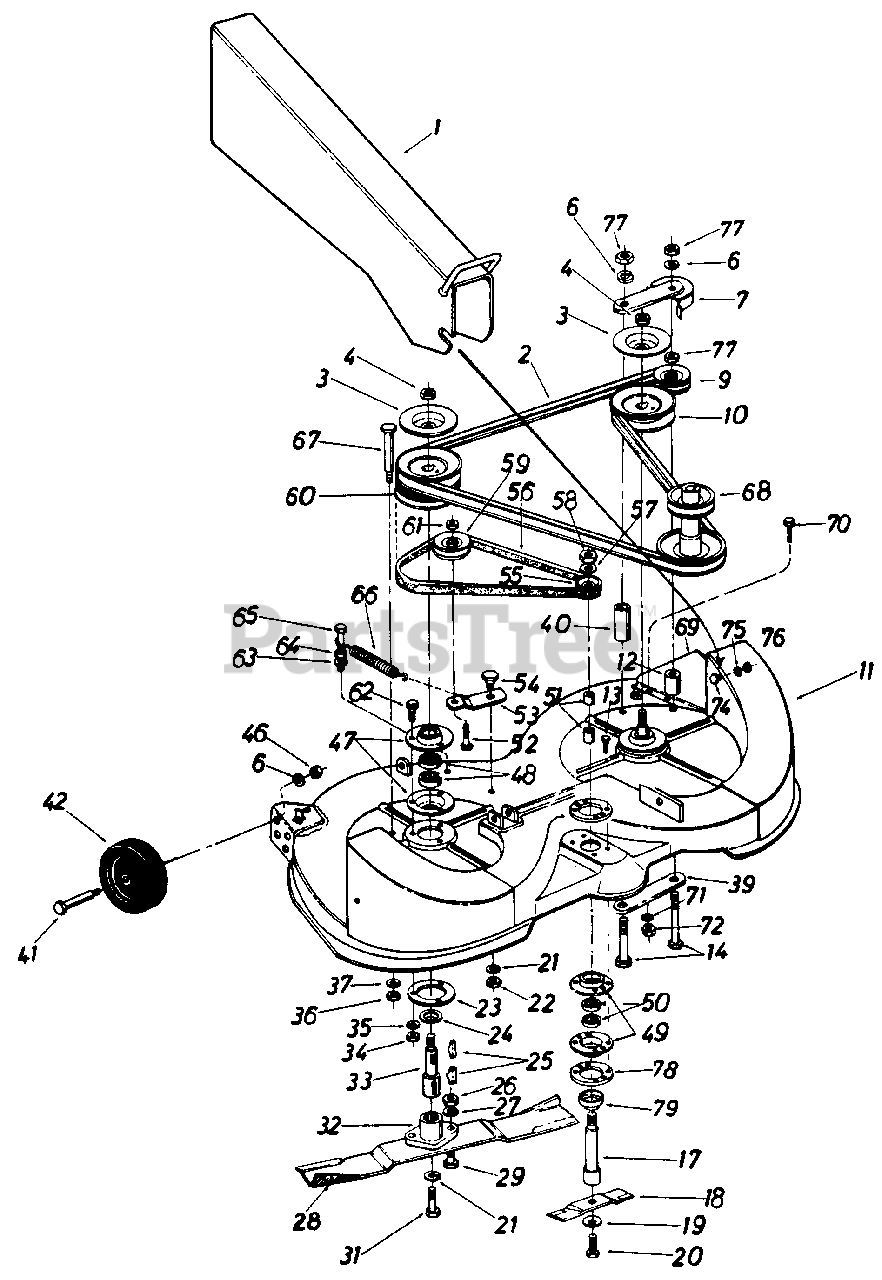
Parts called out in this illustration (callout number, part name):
1	Chute Extension Ass'y. L.H.
2	"V"-Belt
3	Brake Disc
4	Hex Cent. L-Nut 5/8-11 Thd.
6	L-Wash. 3/8" I.D.
7	Idler Pulley Belt Guard Ass'y.
9	5/8-V Belt Idler 8.50" O.D.
10	5/8-V Pulley .628N I.D. x 5.25" O.D.
11	40" Rear Discharge Deck
12	Spacer .40" I.D. x 1.25" O.D. x 1.59" Lg.
13	Hex B-Tap Scr. 1/4" x 1.0"
14	Hex Bolt 3/8-24 x 3.75" Lg.
17	Blade Spindle
18	6.50" Blade
19	Bell-Wash. 40" I.D. x .88" O.D.
20	Hex Bolt 3/8-24 x .87" Lg.
21	L-Wash. 3/8" I.D.
22	Hex L-Nut 3/8-16 Thd.
23	Plate Deck Reinforcement
24	Bearing Shield
25	#6 Hi-Pro Key 5/32 x 5/8" Dia.
26	Hex Nut 5/16-24 Thd.
27	L-Wash. 5/16" I.D.
28	20" High Lift Blade R.H.
29	Hex Bolt 5/16-24 x l.OO" Lg. (Grade 5)
31	Hex Bolt 3/8-24 x 1.50" Lg. (Grade 5)
32	Blade Adapter Kit
33	Blade Spindle
34	Hex Nut 5/16-18 Thd.
35	L-Wash. 5/16" I.D.
36	Hex L-Nut 3/8-16 Thd.
37	L-Wash. 3/8" I.D.
39	Reinforcement Plate
40	Spacer 3/8" I.D. x 50" O.D. x 2.72"
41	Shld. Bolt .498" Dia. x 1.53" Lg.
42	Cutting Deck Wheel
46	Hex Jam Nut 3/8-16 Thd.
47	Bearing Housing
48	Ball Bearing .787" I.D. x 1.85" O.D.
49	Bearing Housing
50	Ball Bearing .53" I.D. x 1.38" O.D.
51	Spacer 63" I.D. x .88" O.D. x .57" Lg.
52	Hex Bolt 3/8-16 x 1.25" Lg.
53	Idler Bracket
54	Shld. Bolt .625" Dia. x .170"
55	3/8" V-Pulley .628" I.D. x 2.00" O.D.
56	"V"-Belt
57	Bell-Wash. 53" I.D. x 1.05" O.D.
58	Hex Jam Nut 5/8-11 Thd.
59	1/2" V-Belt Idler 2.625" O.D.
60	Double Pulley
61	Hex Top L-Jam Nut 3/8-16 Thd.
62	Hex Sems Bolt 5/16-18 x 1.00" Lg.
63	L-Wash. 1/4" I.D.
64	Hex Nut 1/4-20 Thd.
65	Hex Bolt 1/4-20 x 1.00" Lg.
66	Ext. Spring 50" O.D. x 3.97" Lg.
67	Shld. Bolt 498" Dia. x 2.63" Lg.
68	Two Step Engine Pulley
69	Inner Chute Extension L.H.
70	Hex Sems Scr. 1/4-28 X .62" Lg.
71	L-Wash. 1/4" I.D.
72	Hex Nut 1/4-28 Thd.
74	Shld. Scr. 500" Dia. x .218
75	L-Wash. 3/8" I.D.
76	Hex Jam Nut 3/8-16 Thd.
77	Hex Nut 3/8-24 Thd.
78	Reinforcement Plate
79	Bearing Shield
